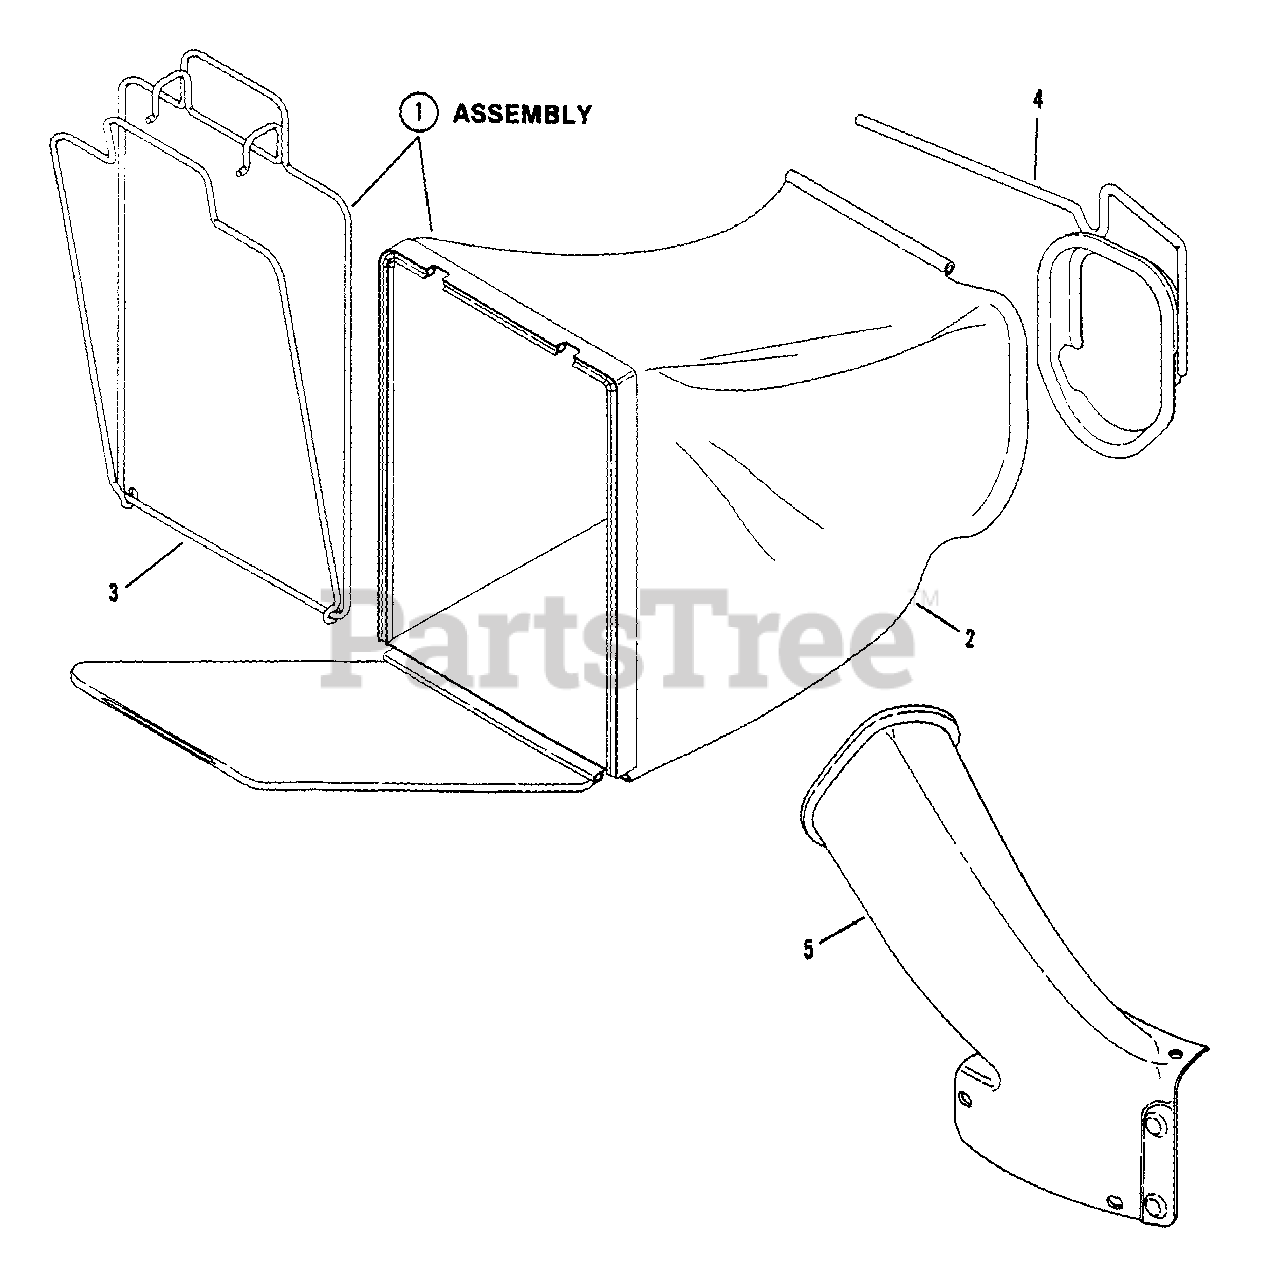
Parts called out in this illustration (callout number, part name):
1	ASSEMBLY, Grass Bag (Door Type)
2	BAG, KWIK-N-EZY
3	ASSEMBLY, Bag Wire
4	CONNECTOR, Grass Bag
5	ADAPTER, Bag
